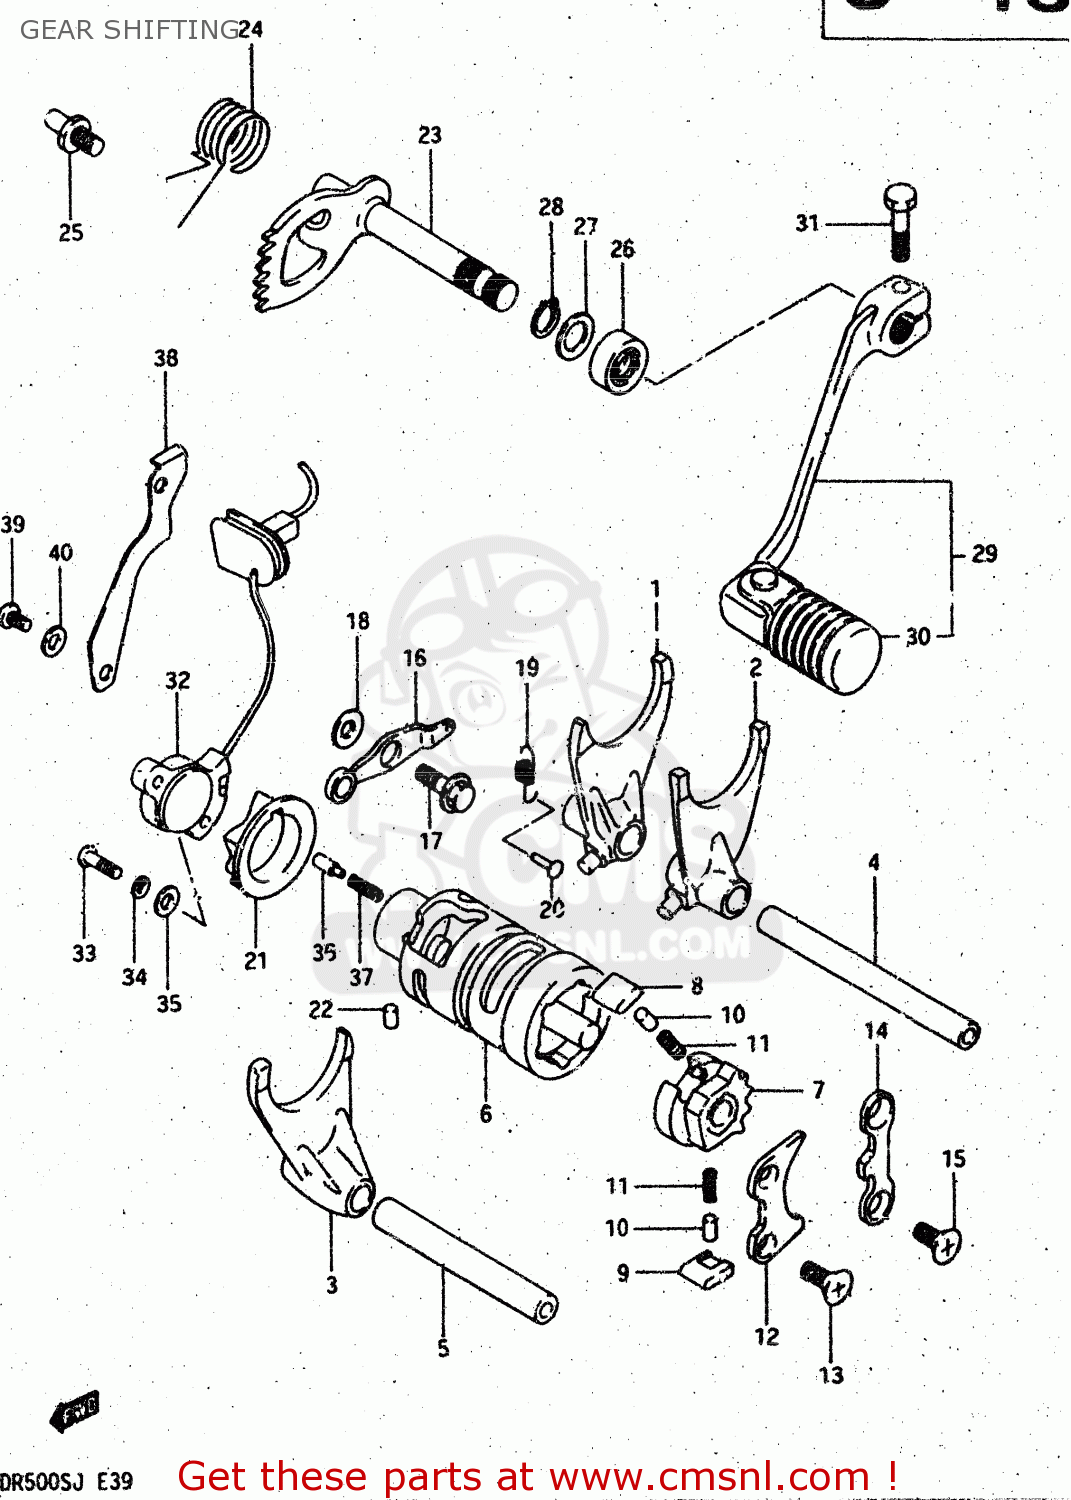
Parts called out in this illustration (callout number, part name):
1	FORK,GEAR SHIFT NO.1
2	FORK,GEAR SHIFT NO.2
3	FORK,GEAR SHIFT NO.3
4	SHAFT,GEAR SHIFT FORK
5	SHAFT,GEAR SHIFT FORK
6	CAM,GEAR SHIFT
7	GEAR,GEARSHIFT CAM DRIVE
8	PAWL,GEAR SHIFT NO.1
9	PAWL,GEAR SHIFT NO.2
10	PIN(5X8)
11	SPRING
12	LIFTER,GEAR SHAFT PAWL
13	SCREW
14	STOPPER,GEAR SHIFT POLE
15	SCREW
16	STOPPER,GEAR SHIFT CAM
17	BOLT
18	WASHER
19	SPRING
20	RIVET
21	PLATE,SHIFT CAM STOPPER
22	PIN 4X6
23	SHAFT,GEAR SHIFT
24	SPRING
25	STOPPER,GEAR SHIFT CAM
26	OIL SEAL
27	WASHER
28	CIRCLIP
29	LEVER ASSEMBLY,GEAR SHIFTING
30	RUBBER,GEAR SHIFT PEDAL
31	BOLT
32	TERMINAL BASE,NEUTRAL
33	SCREW
34	LOCK WASHER
35	WASHER
36	PIN(5X15.5)
37	SPRING
38	CLAMP,LEAD WIRE
39	SCREW
40	WASHER,LOCK
